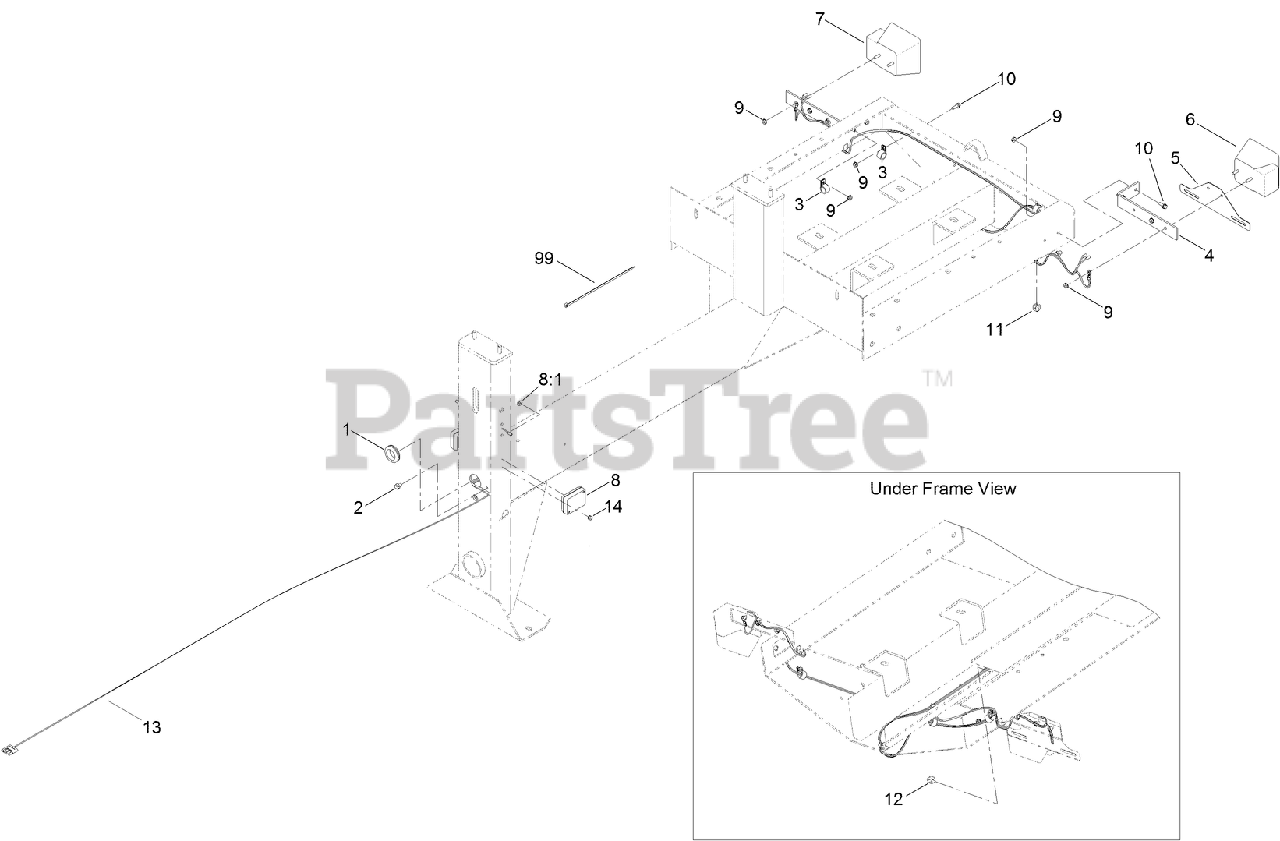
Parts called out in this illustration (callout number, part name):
1	GROMMET
2	CLIP-TIE
3	CLAMP-CABLE
4	BRACKET-UNIVERSAL
5	HOLDER-PLATE, LICENSE
6	LIGHT-TAIL, LH
7	LIGHT-TAIL, RH
8	LAMP-MARKER, FRONT SIDE
8:1	NUT-KEPS
9	NUT-KEPS
10	SCREW-HHF
11	CLIP-EDGE
12	CLIP-EDGE W/TIE, PERPENDICULAR
13	HARNESS-WIRE
14	GROMMET
99	TIE-CABLE
